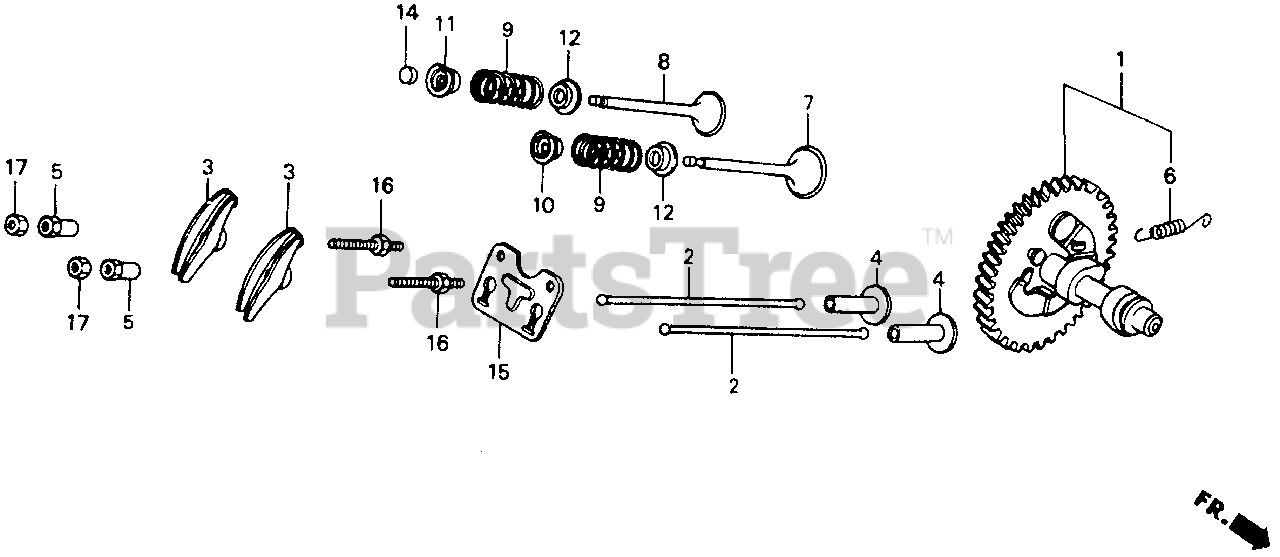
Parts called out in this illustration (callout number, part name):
1	CAMSHAFT ASSY.
2	ROD, PUSH
3	ARM, VALVE ROCKER
4	LIFTER, VALVE
5	PIVOT, ROCKER ARM
6	SPRING, WEIGHT RETURN
7	VALVE, IN.
8	VALVE, EX.
9	SPRING, VALVE
10	RETAINER, IN. VALVE SPRING
11	RETAINER, EX. VALVE SPRING
12	SEAT, VALVE SPRING
14	ROTATOR, VALVE
15	PLATE, PUSH ROD GUIDE
16	BOLT, PIVOT (8MM)
17	NUT, PIVOT ADJ.
